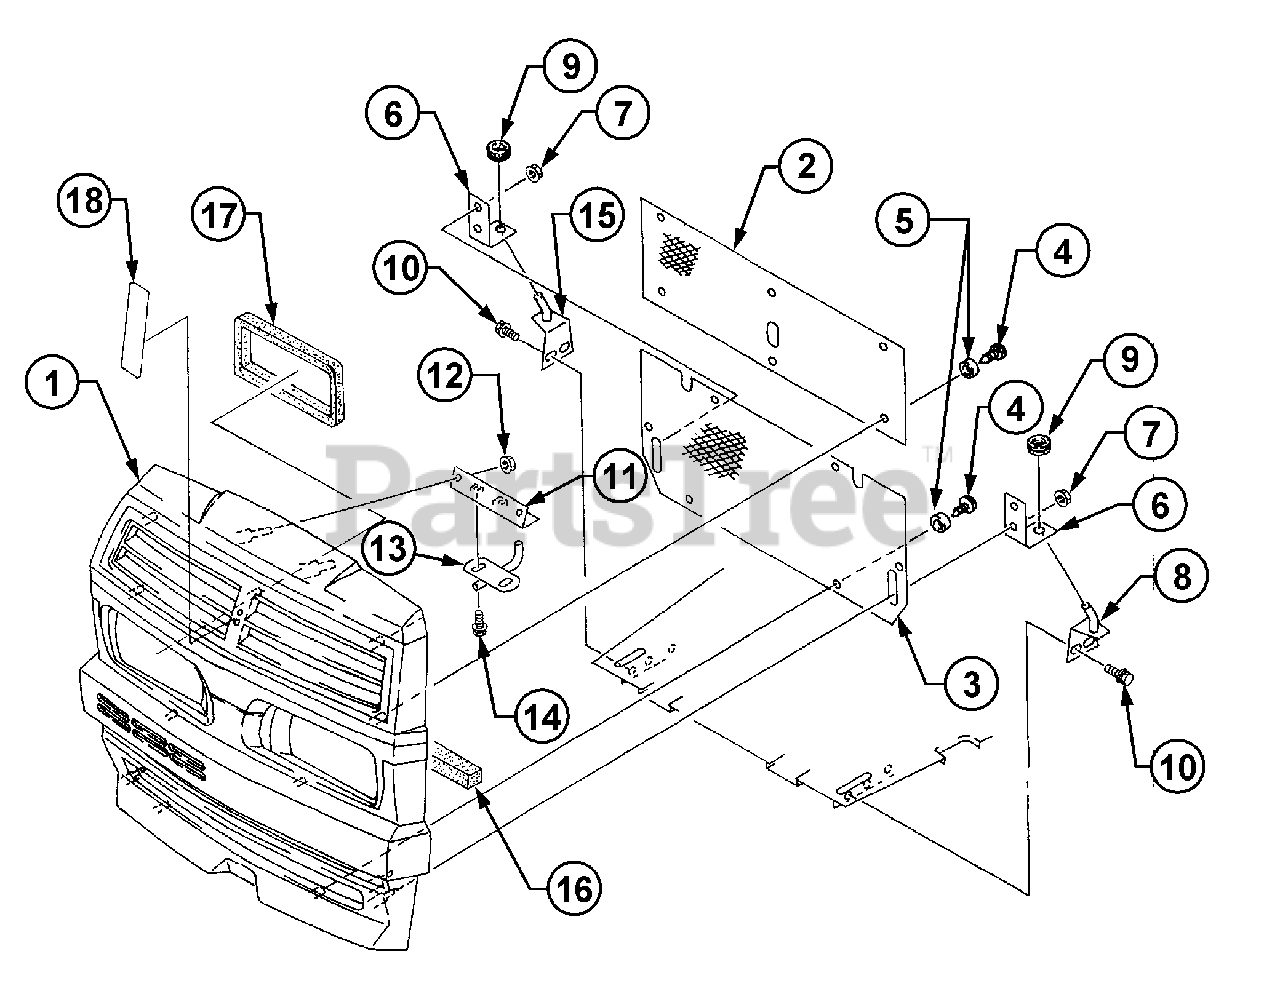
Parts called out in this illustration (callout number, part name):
2	Screen Grille A
3	Screen Grille B
4	Screw, Tapping
8	Plate L.H., Grille
10	Bolt, w/Washer
11	Bracket, Upper
15	Plate R.H., Grille
